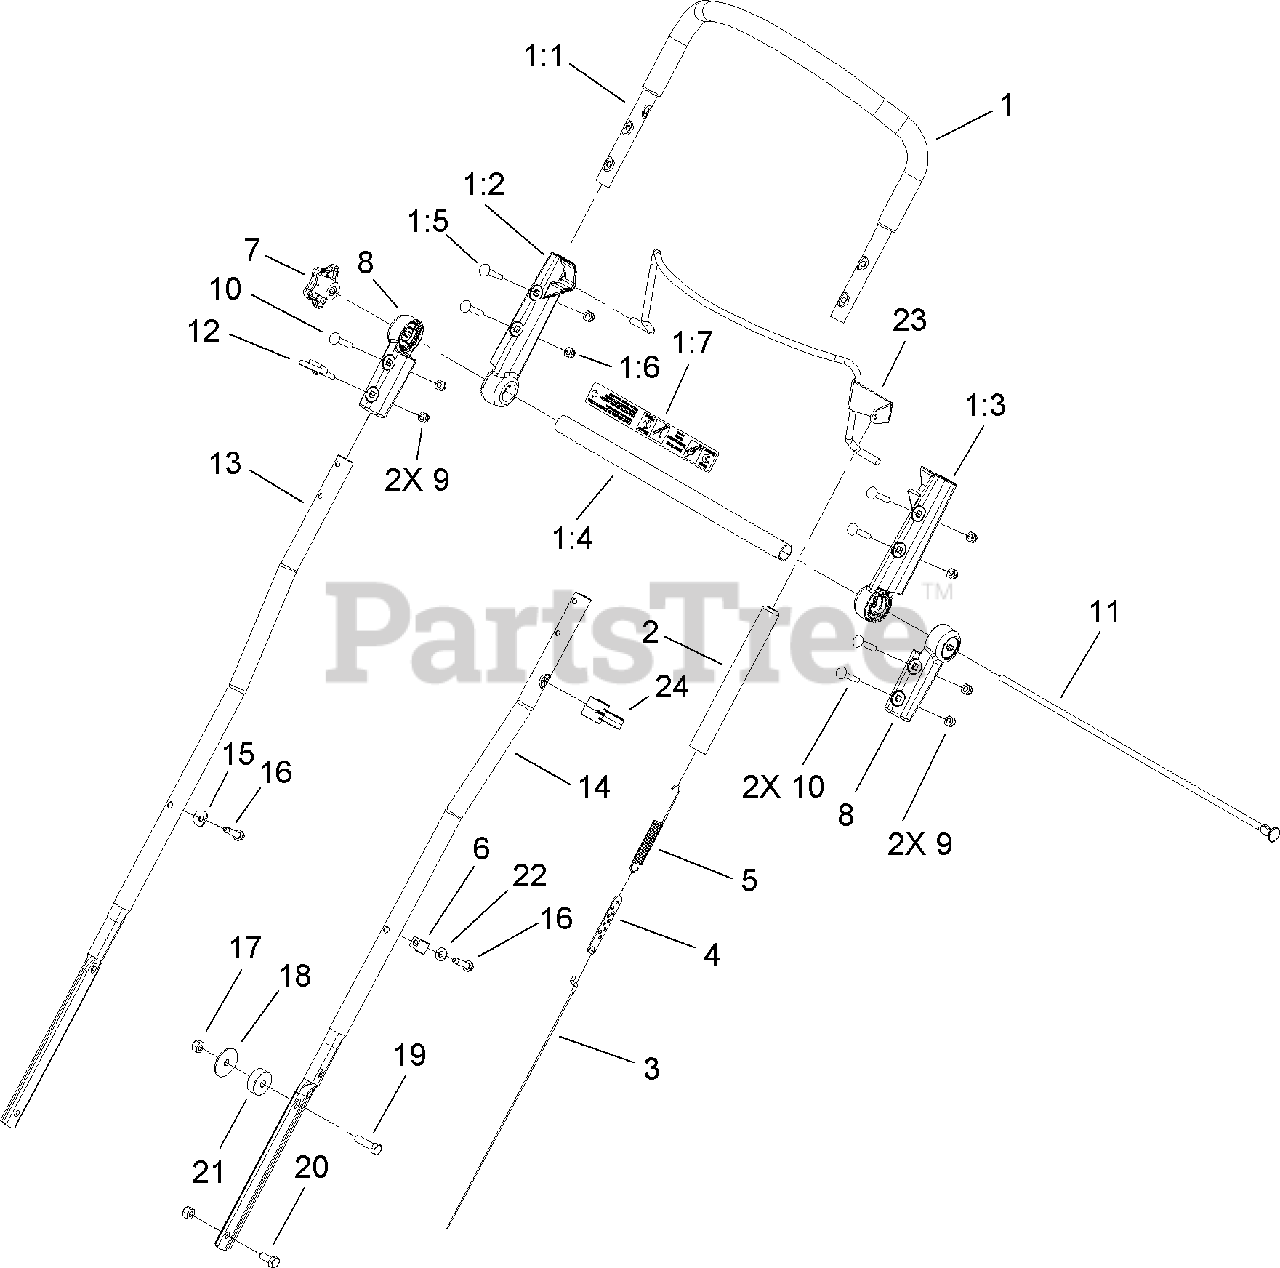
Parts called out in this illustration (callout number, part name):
1	UPPER HANDLE ASM
1:1	HANDLE ASM
1:2	MOUNT-HANDLE, RH
1:3	MOUNT-HANDLE, LH
1:5	SCREW-CARR
1:6	NUT-LOCK, NI
1:7	DECAL-ROTOR DRIVE/HANDLE HEIGHT KNOB
2	COVER-SPRING
3	CABLE-CLUTCH
4	ADJUSTER-CLUTCH CABLE
5	SPRING-CLUTCH
8	MOUNT-HANDLE, LOWER
9	NUT-LOCK, NI
10	SCREW-CARR
11	ROD-THREADED
12	GUIDE-ROPE, UPPER
13	HANDLE-LOWER, RH
14	HANDLE-LOWER, LH
16	SCREW-HWH, TAP
17	NUT-LOCK, NI
18	WASHER-FLAT
19	SCREW-HH
20	SCREW-HH
22	WASHER-FLAT
24	Guide-Cable
